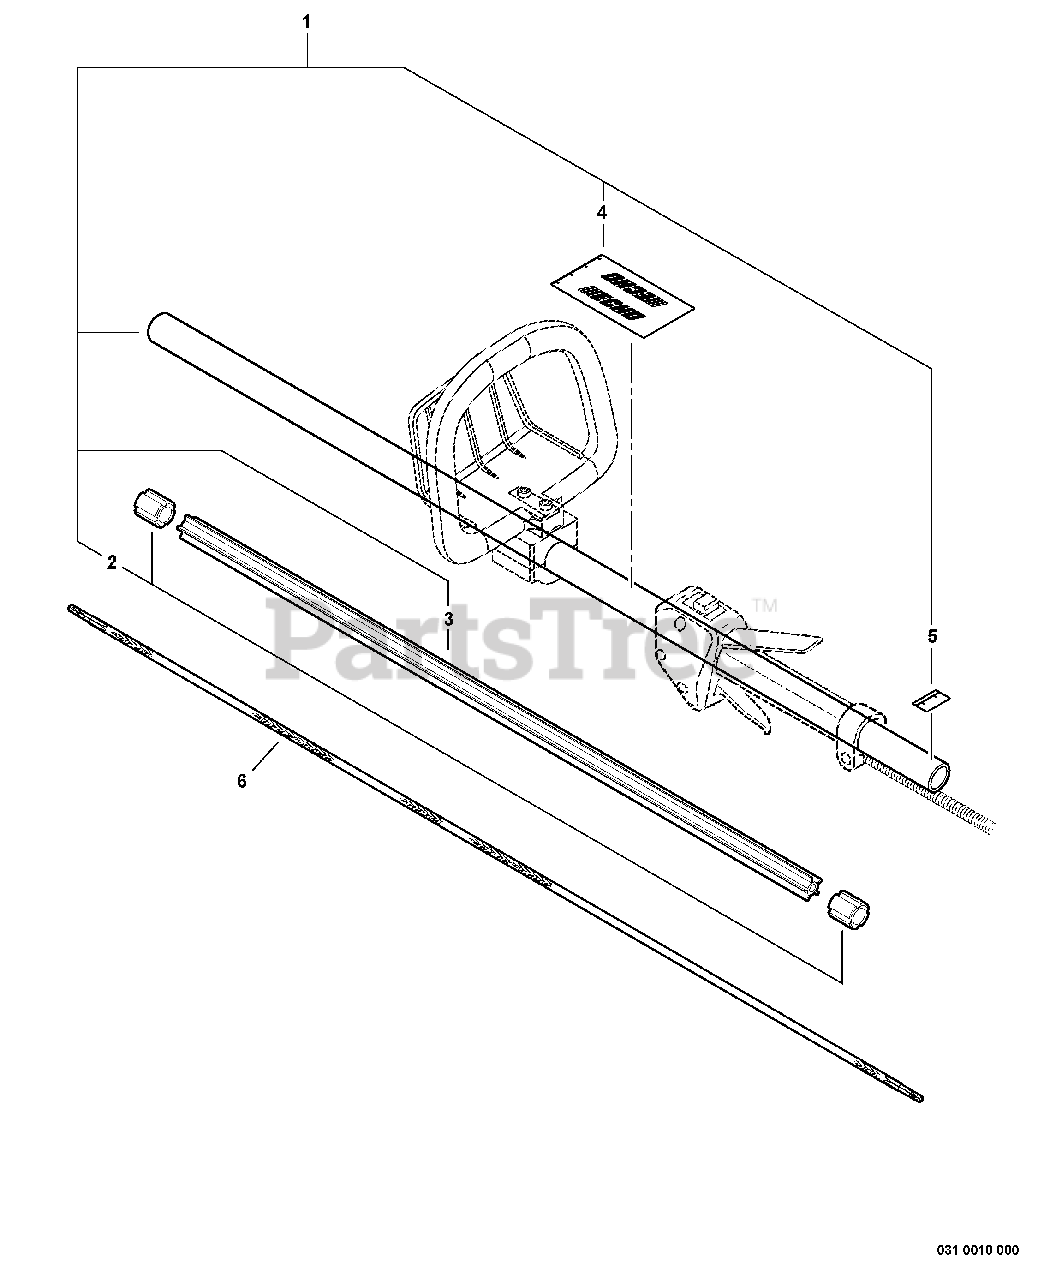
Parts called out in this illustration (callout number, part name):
1	MAIN PIPE ASSY
3	LINER - FLEXIBLE
4	LABEL, HANDLE LOCATION
5	LABEL - ALIGNMENT
6	DRIVESHAFT - FLEXIBLE
